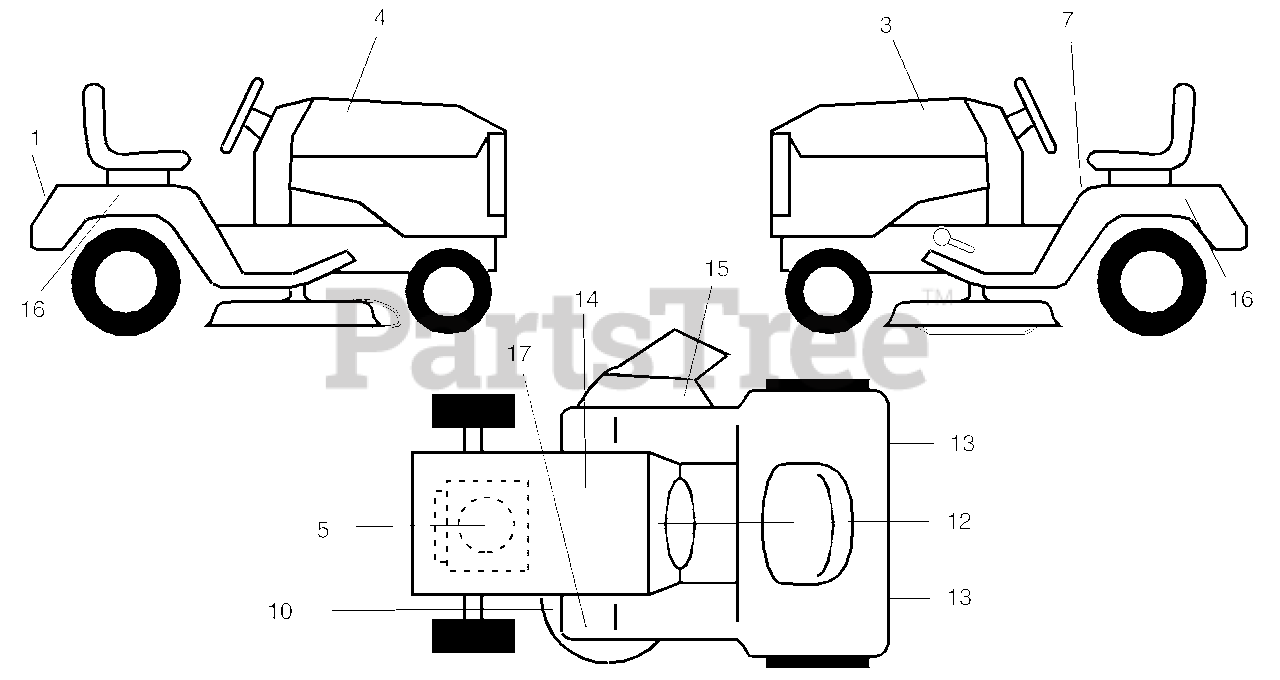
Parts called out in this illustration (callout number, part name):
1	Decal, Fender
3	Decal, Hood LH
4	Decal, Hood RH
5	Decal, HP Engine
7	Decal, Danger Fender English/French
10	Decal, V-Belt Sch
12	Decal, Saddle Oper Instr.
13	Reflector Taillight
14	Decal, Btry Dngr/Psn
15	Decal, Warning Multi-Language
16	Decal, Fender Automatic
17	Decal, Clutch/Brake
